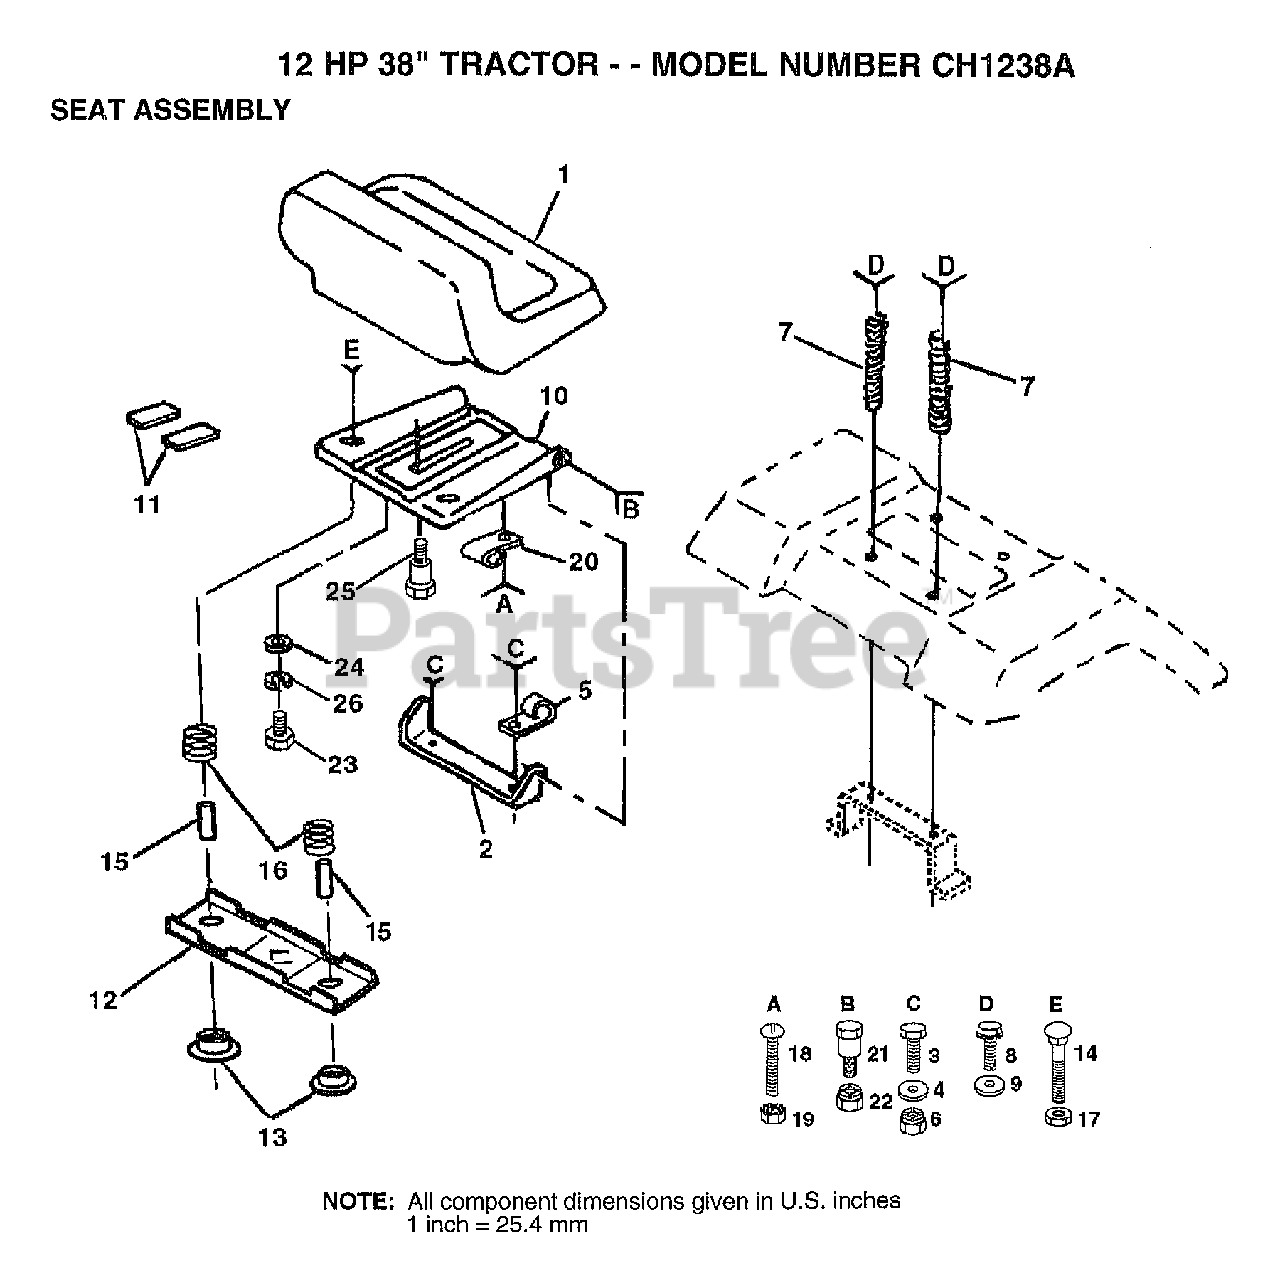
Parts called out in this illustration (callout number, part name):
4	WASHER PM
5	CLIP T
7	SPRING COMPRESSIO
8	SCREW GTV
9	WASHER
11	STRIP FORM
12	BRKT SWITCH
13	BUSHING
15	SPLIT SPACER
16	SPRING
19	"NUT,KEPS"
23	BOLT
24	WASHER
25	"BOLT,SHOULDER"
26	LOCKWASHER
